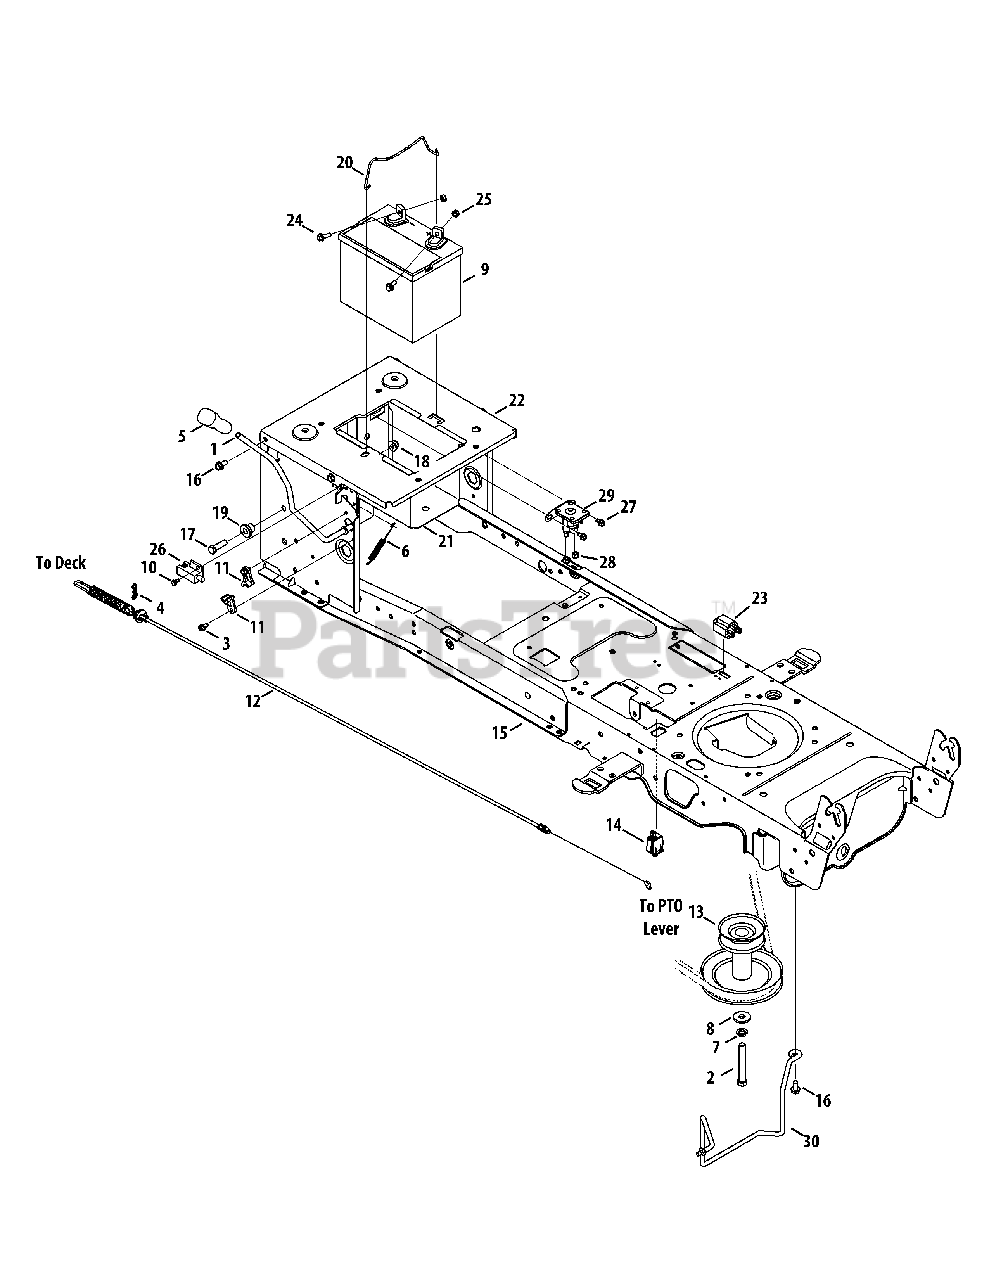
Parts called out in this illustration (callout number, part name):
1	Handle Ass’y, PTO
2	Hex Screw, 7/16-20, 3.50, Gr5
3	Screw, Self-tapping, 1/4-20, 0.50
4	Pin, Cotter, Bow-Tie 72
5	Grip, Handle, Cub
6	Spring, Ext, .38 Dia x 5.6
7	Washer, Lock, 7/16, Regular Duty
8	Washer, Flat, .450 x 1.250 x .164
10	Screw, Shoulder, #10-32, .500
11	Bearing, PTO
12	Cable, Engag, Deck
13	Pulley, Engine, 3.39 x 6.12 Dia.
14	Switch, Plunger, Snap Mount
15	Frame Ass’y, Lower
16	Screw, Self-tapping, 5/16-18, .750,
17	Hex Screw, 3/8-16, 1.50, Gr2
18	Nut, Flange Lock, 3/8-16, Grf,
19	Spacer, Shoulder, .38 x 1.0 x .70
20	Rod, Battery
21	Tray, Battery
22	Bracket, Frame, Seat
23	Switch, 3-Pole
24	Hex Flange Screw, 1/4-20, .75, Gr5
25	Nut, Sems, 1/4-20
26	Switch, Interlock
27	Screw, Self-tapping, 1/4-20, 0.375,
28	Nut, Flange Lock, 1/4-20, Grf,
29	Solenoid, 12V, 100 Amp, 4 term
30	Rod, Keeper
